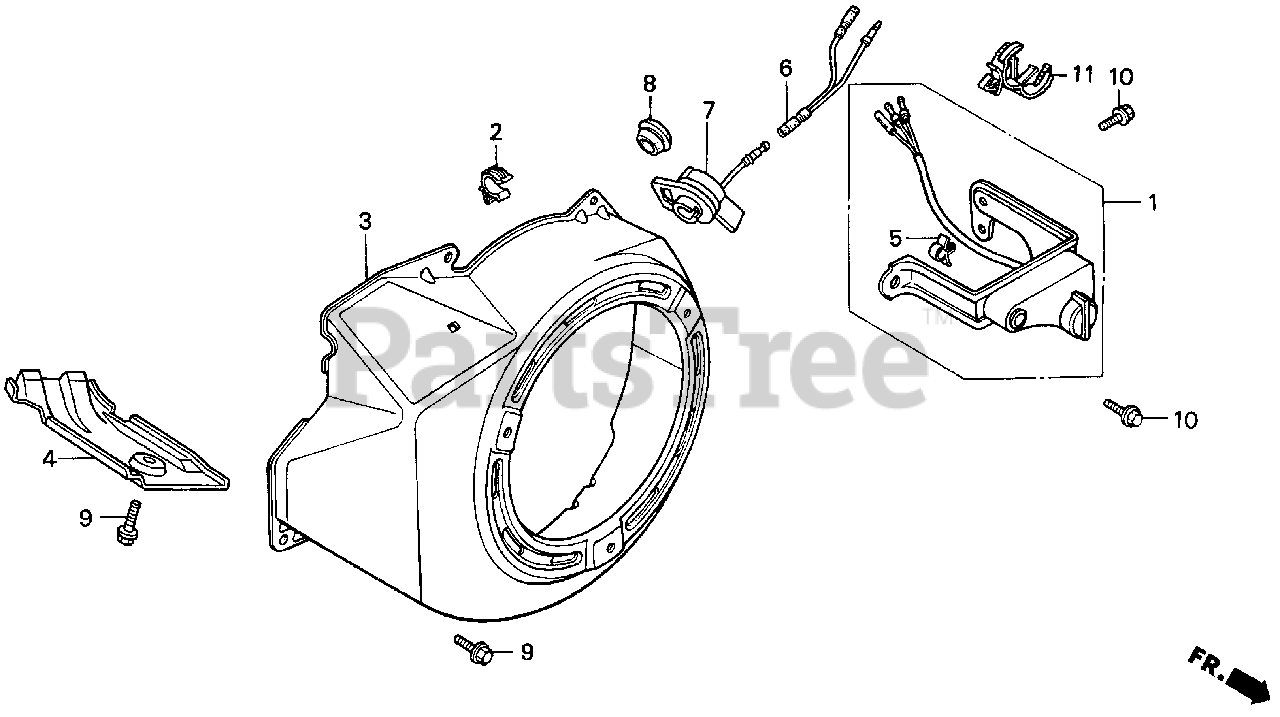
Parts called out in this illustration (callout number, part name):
1	ALERT UNIT, OIL
2	CLIP, TUBE
3	COVER, FAN *R8* (BRIGHT RED)
4	SHROUD
5	CLIP, IGNITION WIRE (8MM)
6	SUB-HARNESS
7	SWITCH ASSY., ENGINE STOP
8	GROMMET, DRAIN HOLE
9	BOLT, FLANGE (6X12) (CT200)
10	BOLT, FLANGE (6X12) (CT200)
11	CLIP, WIRE HARNESS
